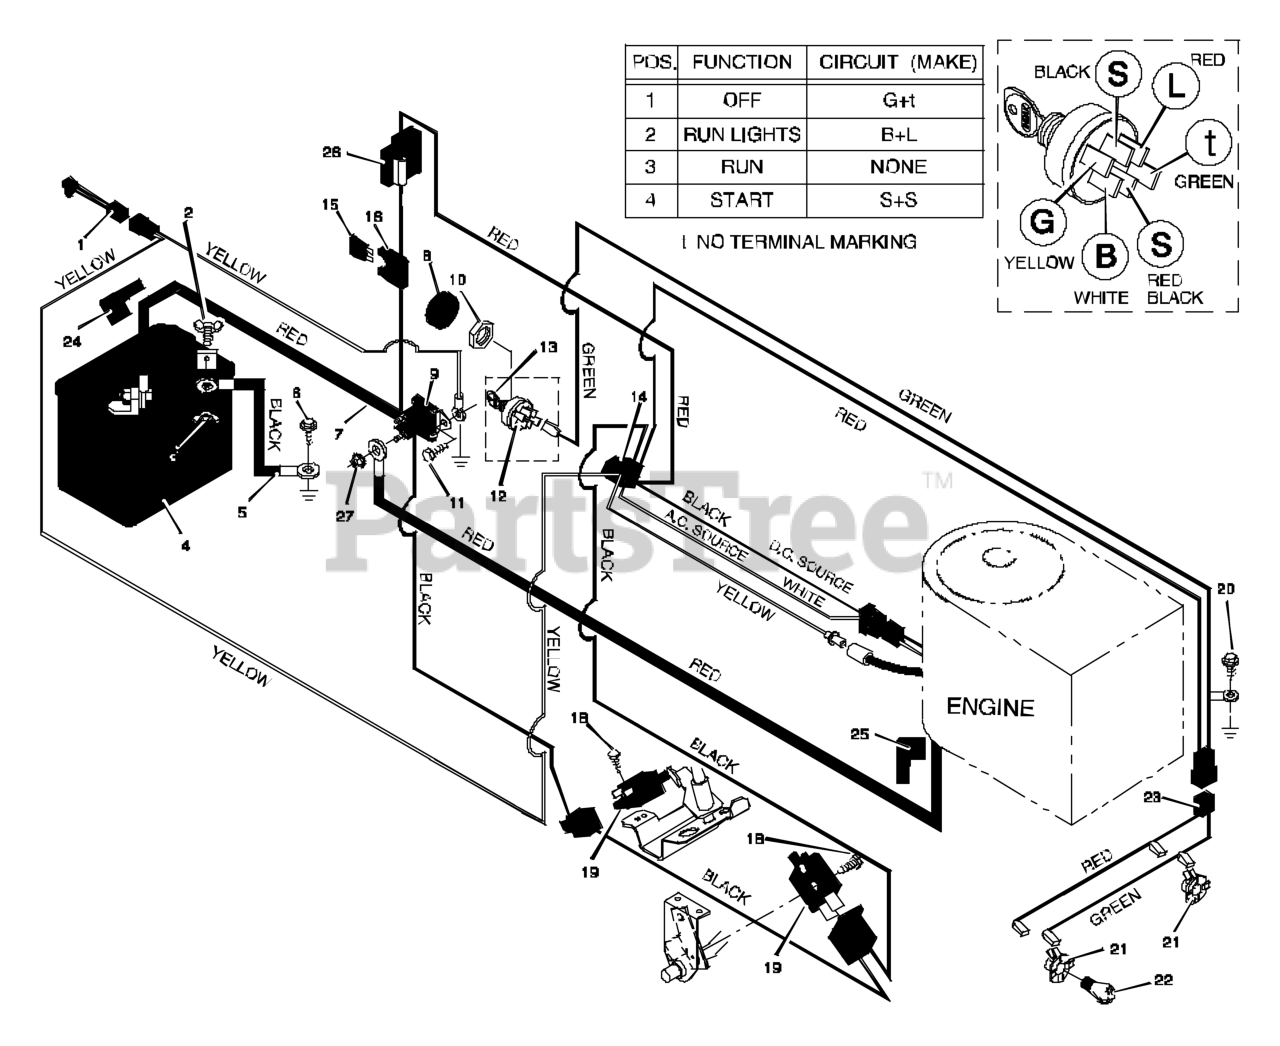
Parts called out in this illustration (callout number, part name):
1	Switch, Seat Sensor
3	Wingnut
4	Battery
5	Cable, Battery Ground
7	Cable, Red Battery
8	Cap, Ignition
9	Solenoid
10	Nut
12	Switch, Ignition
13	Key, Ignition
14	Harness, Chassis Wire
16	Holder, Fuse
19	Switch, Clutch
20	Screw
21	Socket, Light
22	Bulb, Light
23	Harness, Light Wire
24	Cover, Terminal
25	Cover
26	Ammeter
27	Locknut
